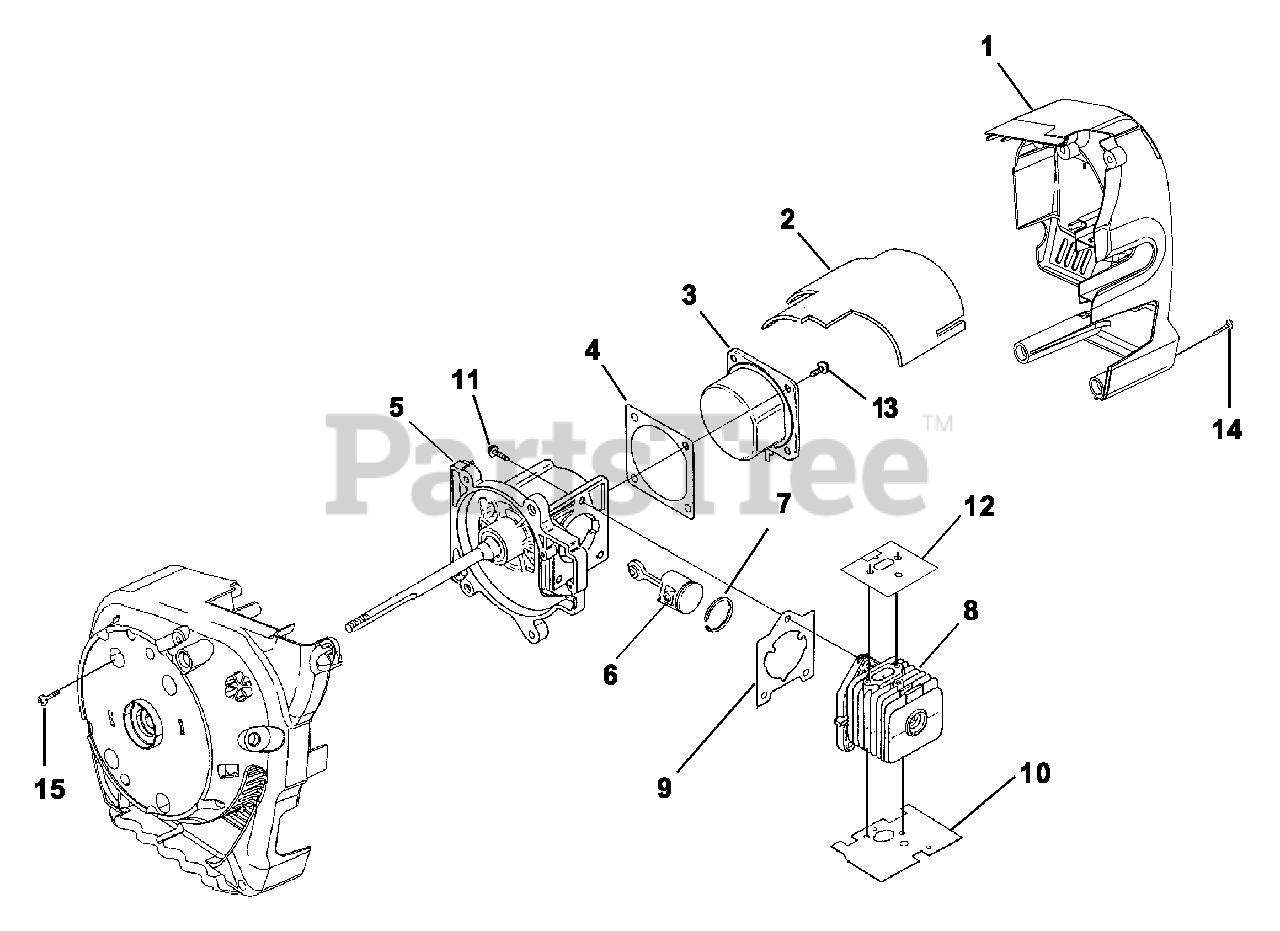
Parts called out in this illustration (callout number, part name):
1	Shroud
2	Heat Shield, Muffler
3	Crankcase Cover
4	Gasket, C/Case
5	Short Block (Svc) (30cc)
5	Short Block (Svc) (25cc)
6	Piston & Rod (30cc)
6	Piston & Rod (25cc)
7	Piston Ring (30cc)
7	Piston Ring (25cc)
8	Cylinder Kit (30cc)
8	Cylinder Kit (25cc)
9	Gasket, Cylinder
10	Gasket, Heaat Dam
11	Screw, Sems (12-24 x 3/4)
12	Gasket, Muffler
13	Screw, Sems (10-24 x .560)
14	Screw, Thread Forming (10-14 x 7/8)
15	Taptite, Truss (10-24 x 3/4)
